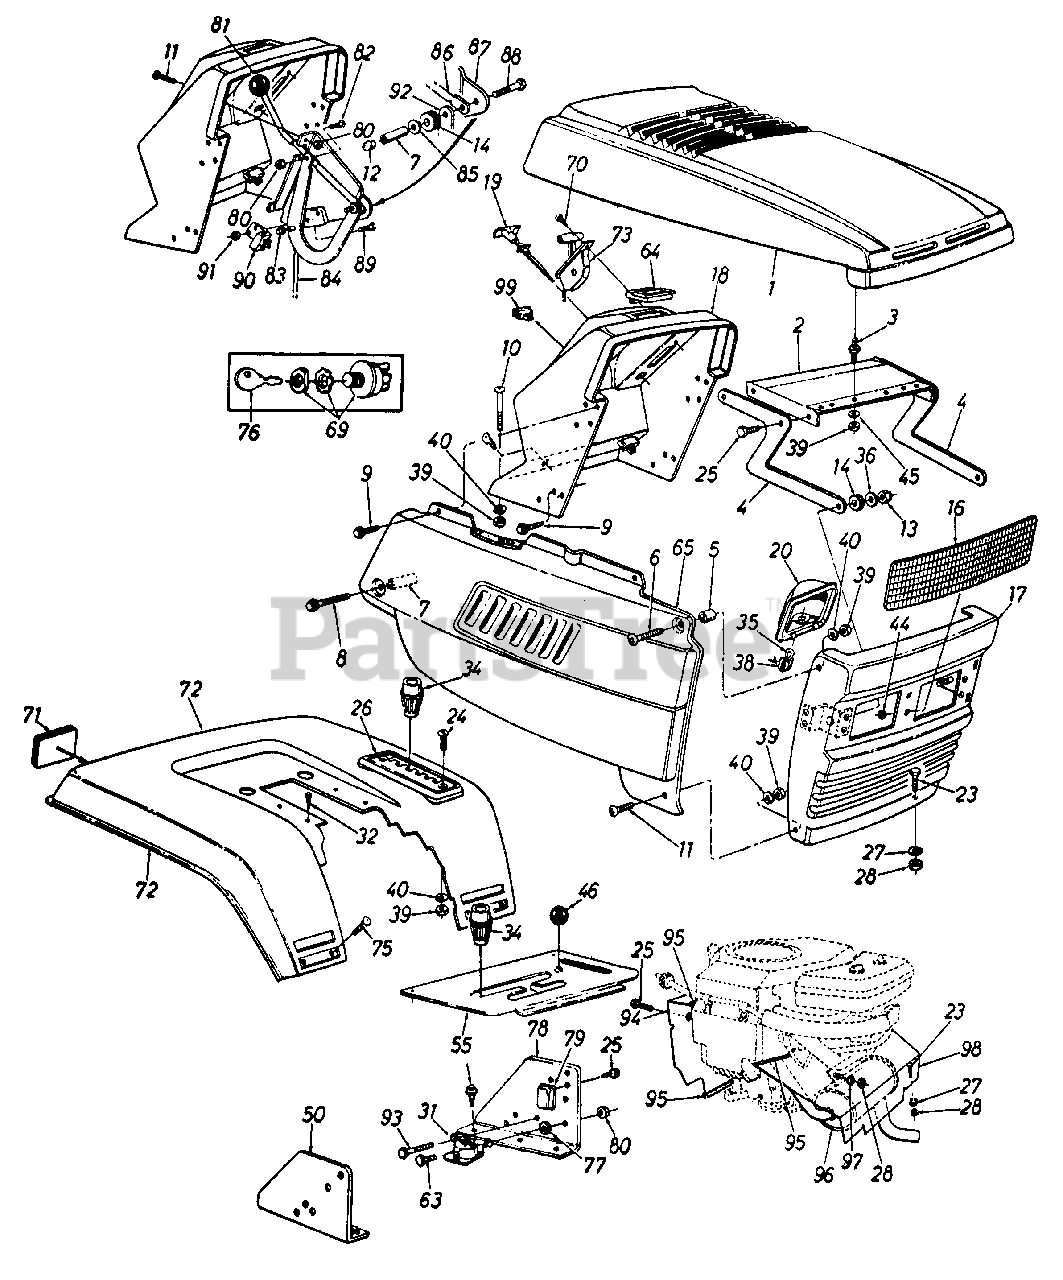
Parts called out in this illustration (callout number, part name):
2	Hood Plate
3	Double Ended Stud 1/4-20 Thd.
4	Hood Hinge
5	Spacer .34" I.D. x .437"
6	Truss Hd. Mach. Scr. 1/4-20 Thd.
7	Spacer.26" I.D. x .375"
8	Hex Wash. TT-Tap Scr. 1/4-20 x 1.75" Lg.
9	Hex T-Tap Scr. 1/4-20 x .75" Lg.
10	Truss Mach. Scr. 1/4-20 x 1.75" Lg.
11	Truss Mach. Scr. 1/4-20 x .5" Lg.
12	Hex Ins. L-Nut 1/4 20 Thd.
13	Hex L-Nut 5/16-18 Thd.
14	Rubber Washer
16	Headlight Lens
19	Choke Control
20	Headlight Housing
23	Hex Bolt 5/16-18 x .75" Lg.
24	Truss Mach. Scr. 1/4-20 x .62n Lg.
25	Hex Wash. Hd. Scr. 1/4" x .5" Lg.
26	7-Speed Index Brkt.
27	L-Wash. 5/16" I.D.
28	Hex Nut 5/16-18 Thd.
31	Solenoid
32	Hex Hd. Rolling Scr. 5/16-24 x ,7sn Lg.
34	Shitt Knob
35	Lamp
36	Bell-Wash. .34" I.D. x 37"
38	Socket
39	Hex Nut 1/4-20 Thd.
40	L-Wash. 1/4" I.D.
44	Speed Nut 5/16" I.D.
45	Bell-Wash. .265" I.D. x .75" O D
46	Ball Knob Brake
50	Dash Support Brkt.-R.H.
55	Transmission Cover Ass'y.
63	Hex Bolt 1/4-20 x .5" Lg.
64	Ammeter
70	Truss Mach. AB-Tap Scr. #10 x .5n Lg.
71	Reflector
75	Carriage Bolt t/4-20 x .5" Lg.
76	Key
77	Ext. L-Wash. 1/4" I.D.
78	Dash Support Brkt.-L.H.
79	Circuit Breaker
80	Hex Sems Nut 1/4-20 Thd.
81	Ball Knob
82	Hex Bolt 1/4-20 x .62" Lg.
83	Push Nut
84	PTO Rod
85	Fl-Wash. .281" I.D. x 73n
86	PTO Lever
87	Deck Clutch Control Brkt.
88	Hex Bolt 1/4-20 x 2 Sn Lg.
89	Truss Mach. Scr. #10-24 x .5" Lg.
90	Safety Switch
91	Hex Nut #10-24 Thd.
92	PTO Bracket
93	Self Clinching Stud 1/4-20 x .5" Lg.
94	Engine Baffle
95	Trim Strip lon Lg.
96	Muffler
97	Spec. L-Wash. 5/16n I.D.
98	Front Heat Shield
99	Light Switch
